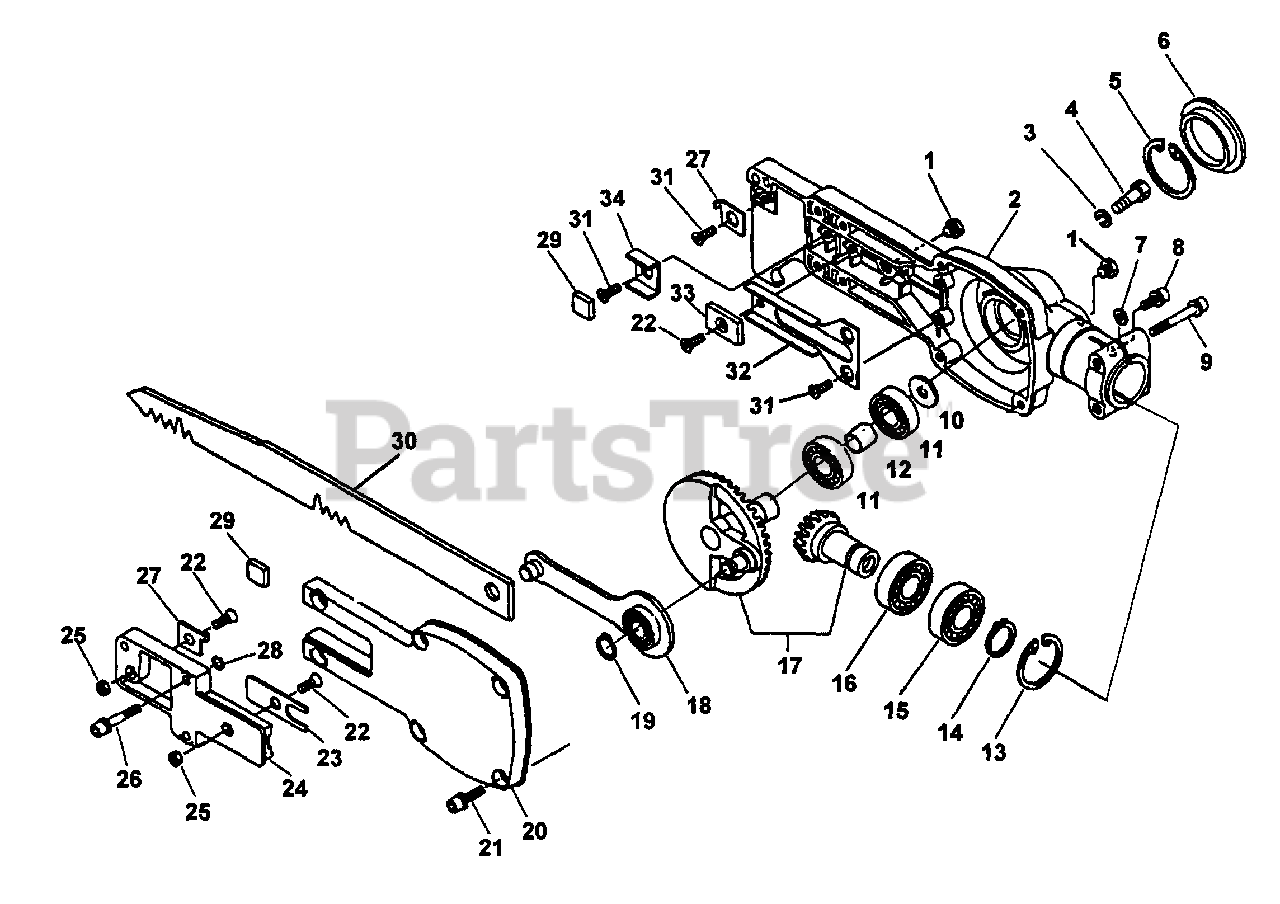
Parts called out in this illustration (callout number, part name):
1	BOLT - 8X8
2	CASE, GEAR
3	LOCKWASHER - 5
4	BOLT - 5X16
5	RING, RETAINING - 26
6	LID, GEAR CASE
8	SCREW - 5X14
9	SCREW - 5X28
10	WASHER - 5
11	BEARING, BALL - 6000Z
13	RING, RETAINING - 24
14	RING, RETAINING - 12
15	BEARING, BALL - 6901Z
16	BEARING, BALL - 6901
17	GEAR SET
18	CONNECTING ROD ASSY
19	RING, RETAINING - 7
20	LID, GEAR CASE
21	SCREW - 5X18
22	SCREW - 4X12
23	GUIDE, BLADE
24	LID, GEAR CASE
26	SCREW - 5X30
27	BLADE, SAW
28	RING, RETAINING
29	SEAL, FELT
30	GUIDE, BLADE
31	SCREW - 4X10
32	GUIDE, BLADE
33	GUIDE, BLADE
34	GUIDE, BLADE
